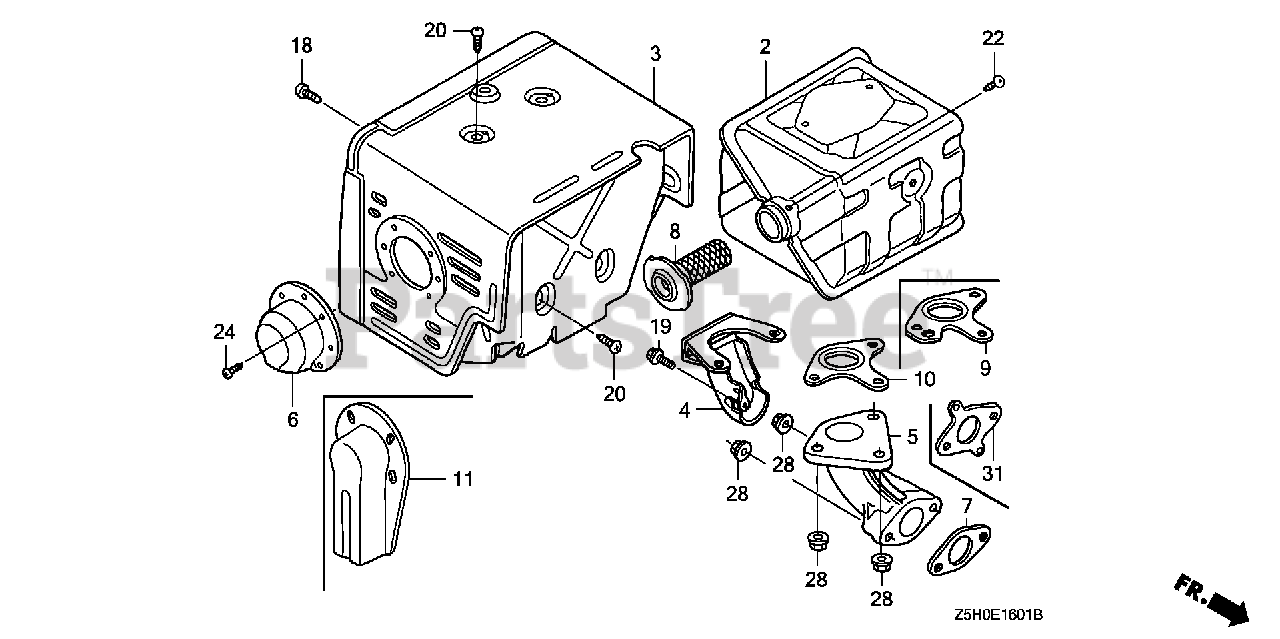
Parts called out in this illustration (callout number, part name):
2	MUFFLER (100DB)
3	PROTECTOR, MUFFLER
8	ARRESTER, SPARK
9	GASKET, MUFFLER (ARRESTER) (NIPPON LEAKLESS)
10	GASKET, MUFFLER (NIPPON LEAKLESS)
18	SCREW, TAPPING (6X10)
20	SCREW, TAPPING (5X8)
22	SCREW, TAPPING (4X6)
28	NUT, FLANGE (8MM)
31	GASKET, EX. PIPE
